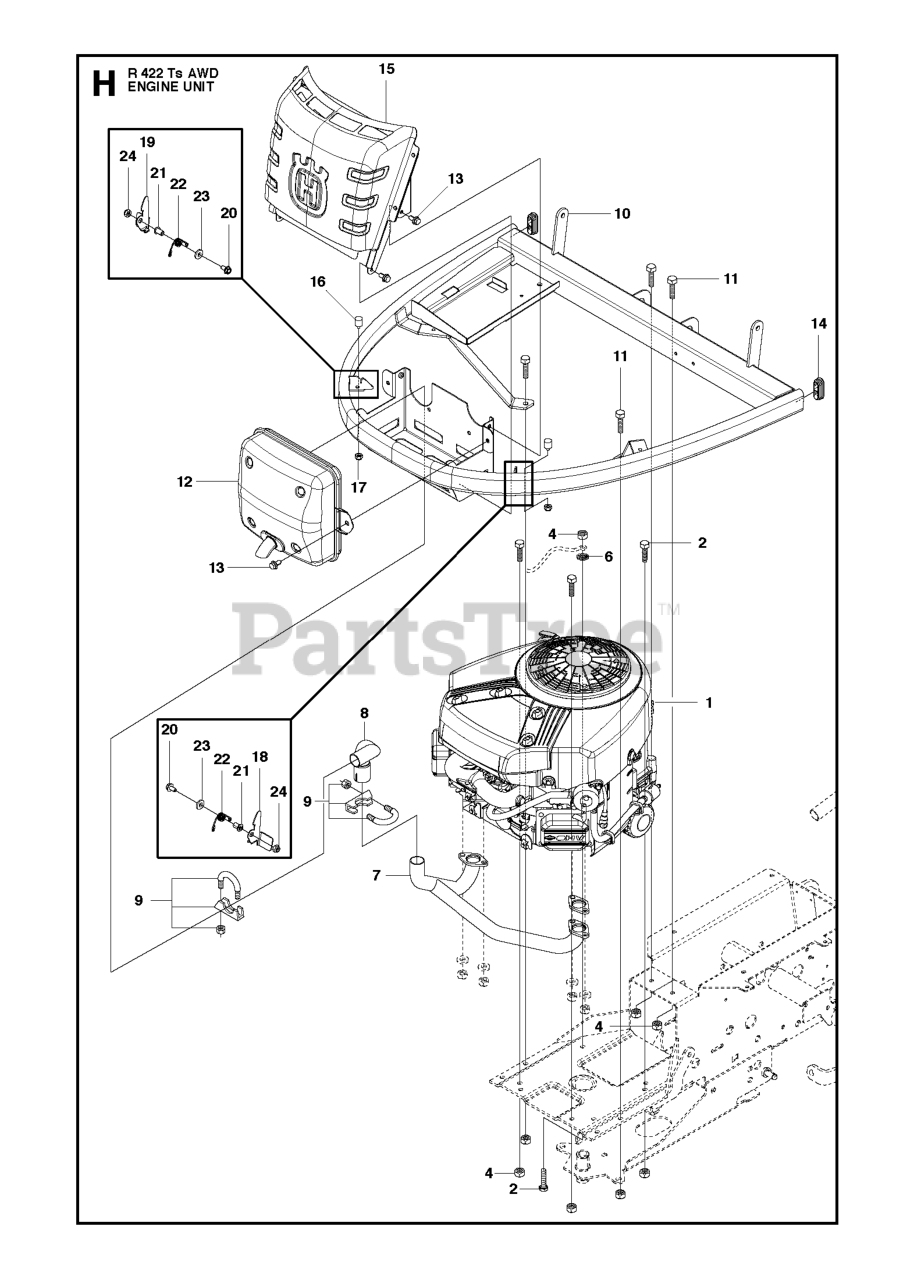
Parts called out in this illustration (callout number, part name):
4	LOCKNUT M8
9	CLAMP
13	SCREW EHHFM
17	LOCKNUT M5
23	WASHER - 26X6.5X1.6
24	LOCKNUT M6
